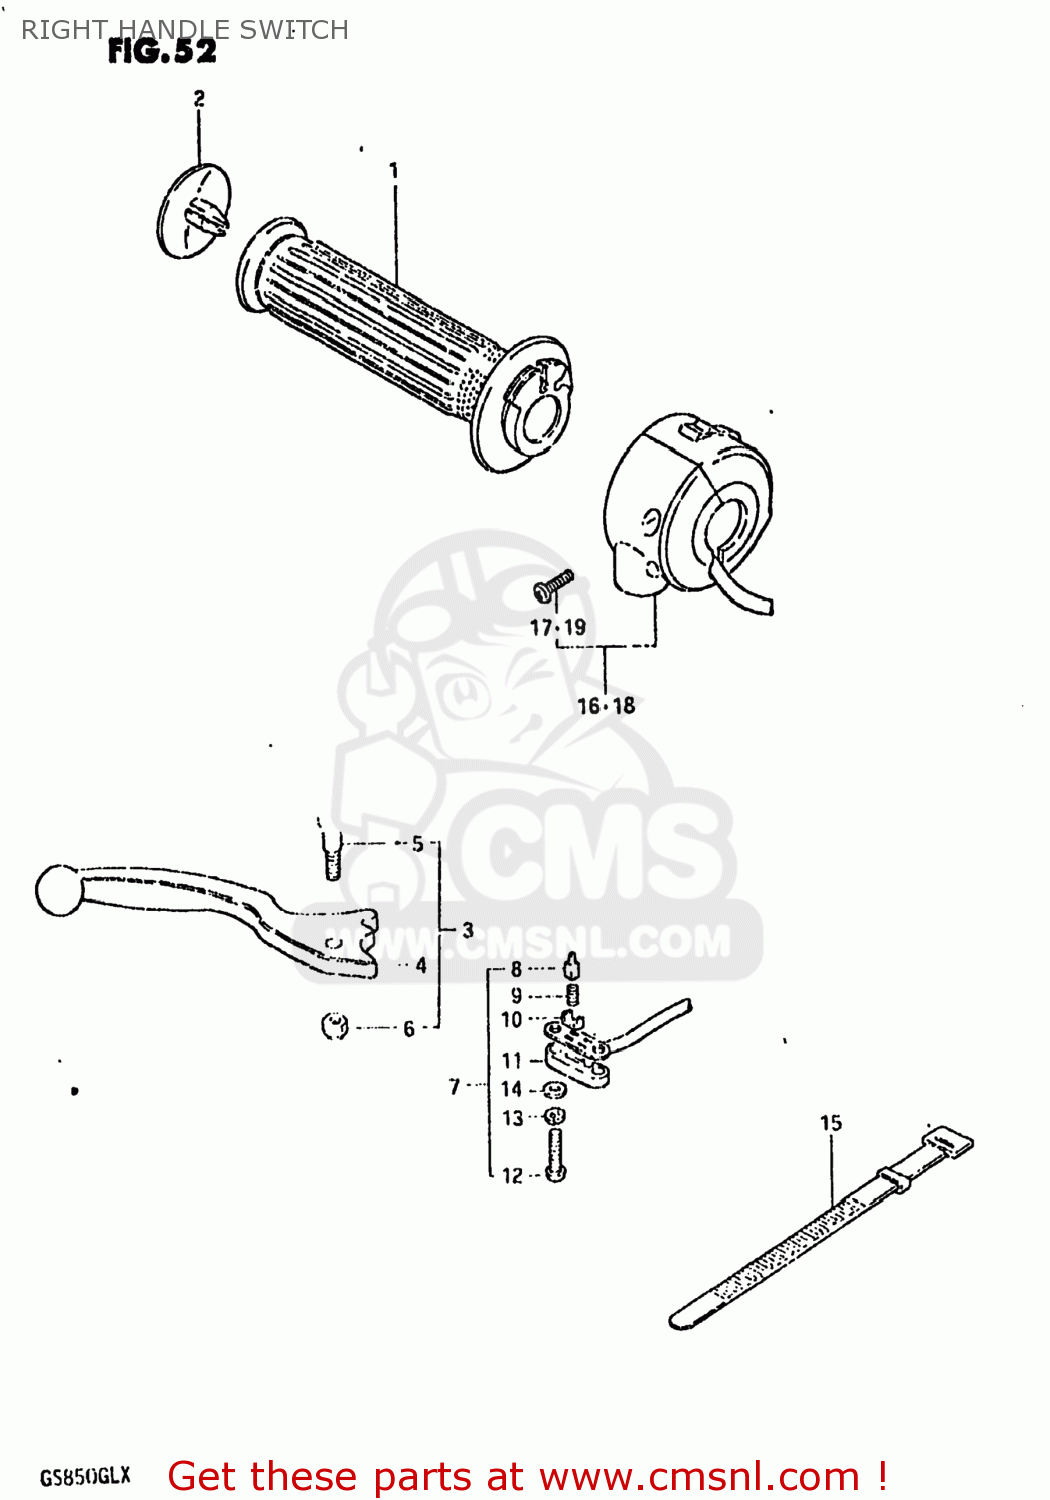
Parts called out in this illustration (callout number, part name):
1	GRIP,THROTTLE
2	CAP,GRIP END
3	LEVER ASSEMBLY,BRAKE
4	LEVER,BRAKE
5	BOLT
6	NUT 6MM
7	SWITCH ASSEMBLY
8	HOLDER
9	SPRING
10	PLATE
11	COVER,FR BK TERMINAL BASE
12	SCREW
13	LOCK WASHER
14	WASHER
15	CLAMP(L:120)
16	SWITCH ASSEMBLY,HANDLE,RIGHT
17	SCREW
18	SWITCH ASSEMBLY,HANDLE,RIGHT
19	SCREW
